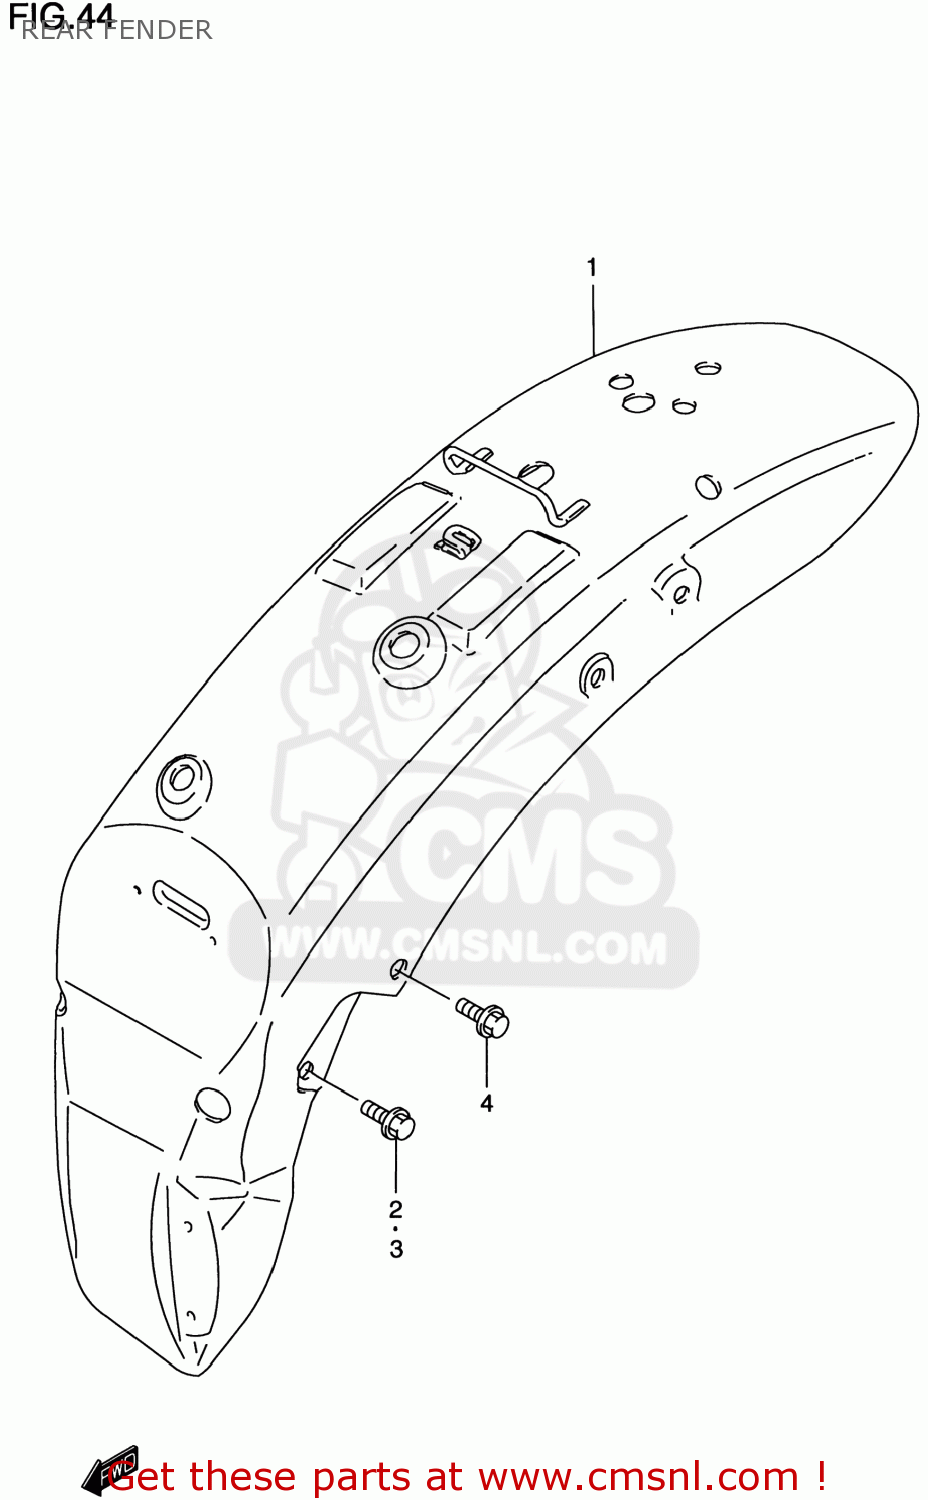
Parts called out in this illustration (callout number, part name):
1	FENDER COMP,REAR
2	BOLT
3	BOLT
4	BOLT
